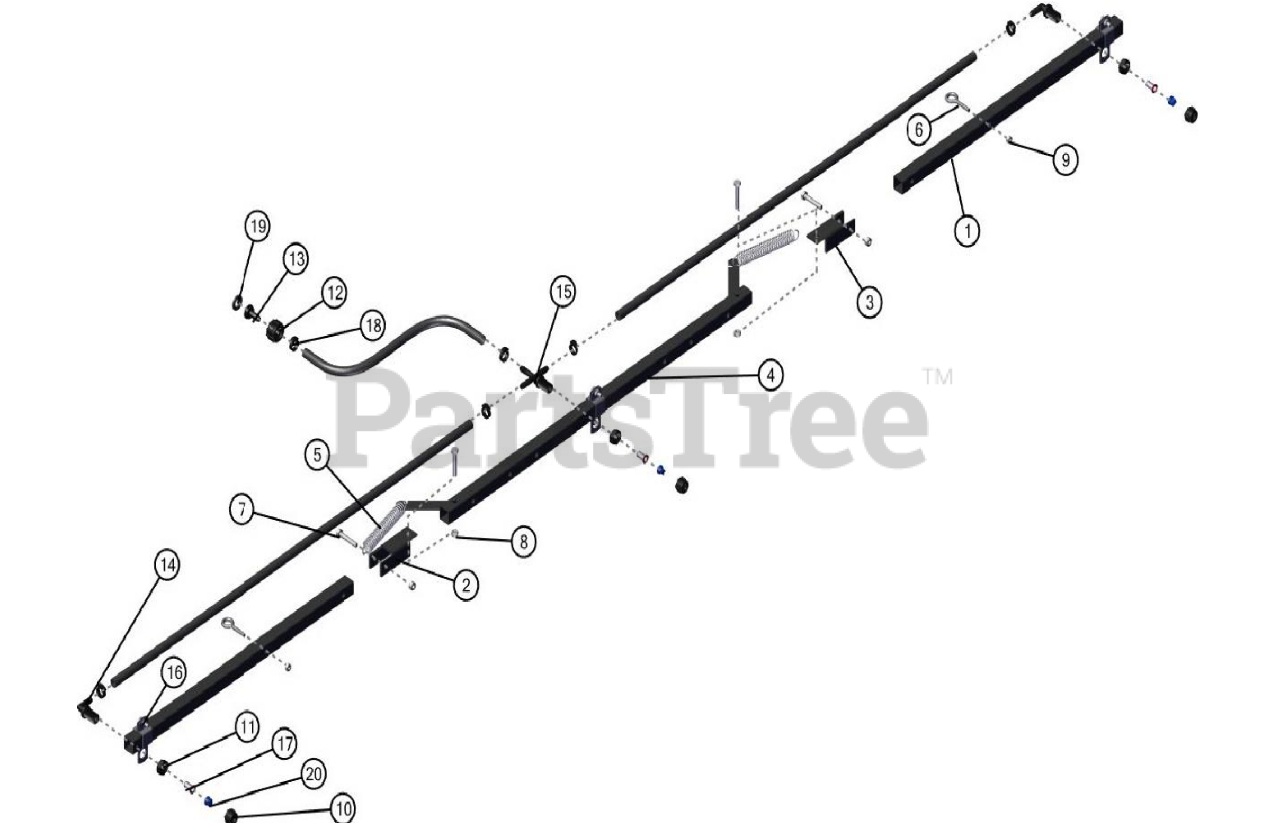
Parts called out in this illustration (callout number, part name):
1	ASSEMBLY
2	BREAKAWAY BOOM - LH
3	BREAKAWAY BOOM - RH
5	EXTENSION SPRING .75 ODX6.5"
6	EYEBOLT 1/4"
7	BOLT 5/16-18X1.75"
8	LOCK NUT 5/16-18
9	NUT 1/4-20 SF
10	NOZZLE NUT 11/16" FPS POLY
11	POLY NOZZLE NUT 11/16"
12	KNURLED SWIVEL NUT 3/4"
13	FLAT SEAT HOSE BARB 3/8" HB
14	ELBOW 11/16"MPSX3/8"HB
15	HOSE BARB CROSS FITTING 11/16" x 3/8"
16	SQUARE BOOM CLAMP 1"
17	RED NOZZLE STRAINER 50M
18	SNAPPER HOSE CLIP
19	WASHER 1"ODX3/4"ID
20	COMPRESSION FAN TIP 80D
